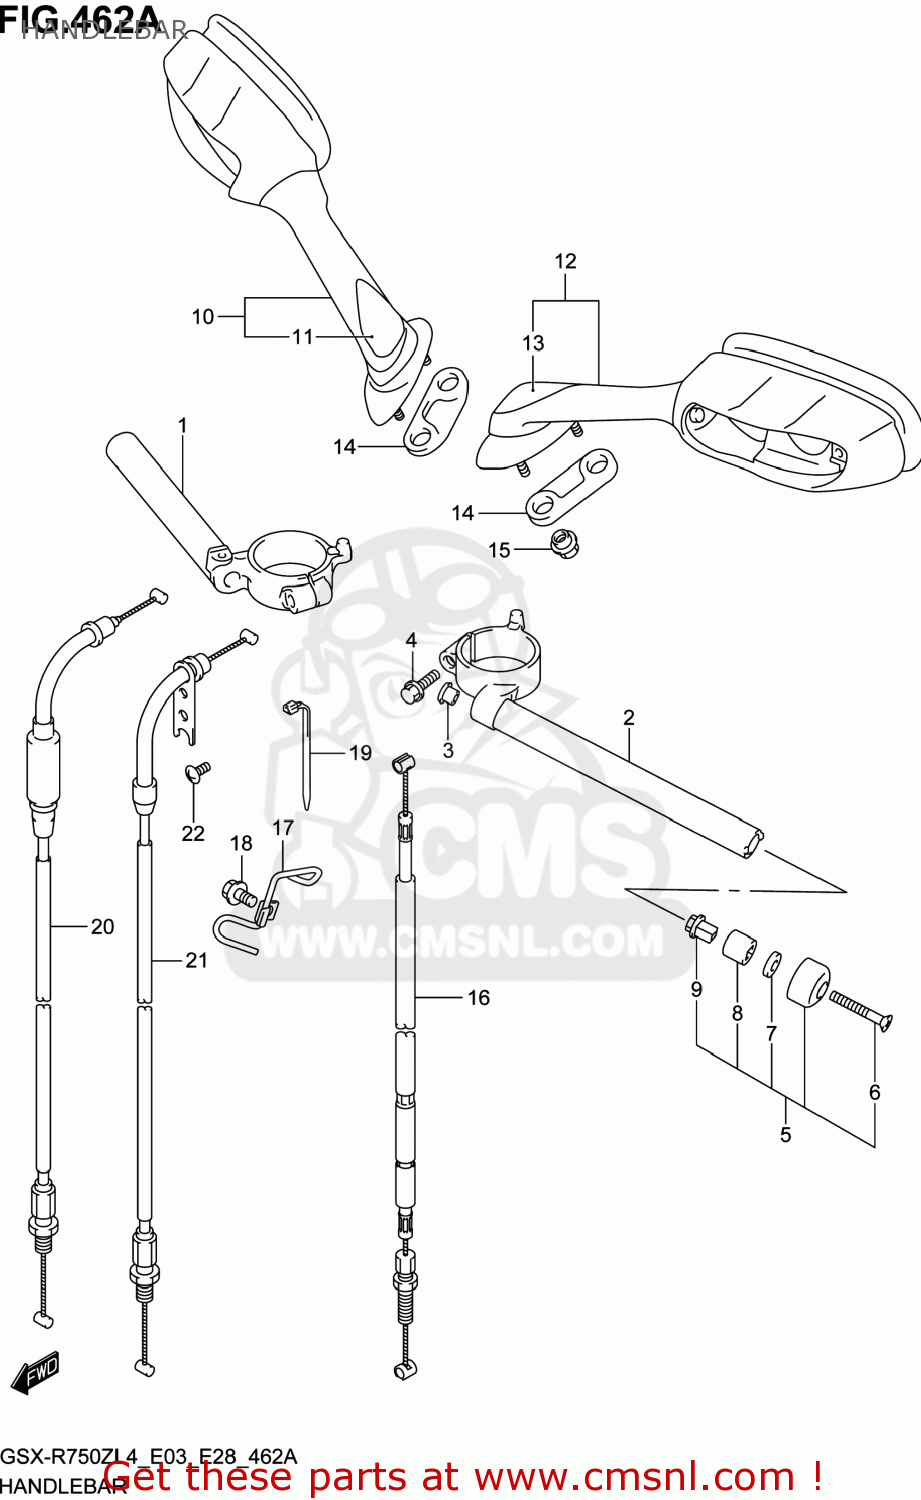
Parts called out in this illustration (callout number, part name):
1	HANDLEBAR,R
2	HANDLEBAR,L
3	CAP,HANDLEBAR
4	BOLT(8X32)
5	BALANCER SET,HANDLEBAR
6	SCREW
7	WASHER(6.5X16X4)
8	EXPANDER,HANDLE BALANCER
9	NUT,HANDLE BALANCER
10	MIRROR ASSY,RR VIEW,R
11	CAP,R
12	MIRROR ASSY,RR VIEW,L
13	CAP,L
14	CUSHION,RR VIEW MIRRROR,R
15	NUT,RR VIEW MIRROR
16	CABLE ASSY,CLUTCH
17	GUIDE,CABLE
18	BOLT
19	CLAMP(L:154)
20	CABLE ASSY,THROTTLE NO.1
21	CABLE ASSY,THROTTLE NO.2
22	SCREW(5X10)
